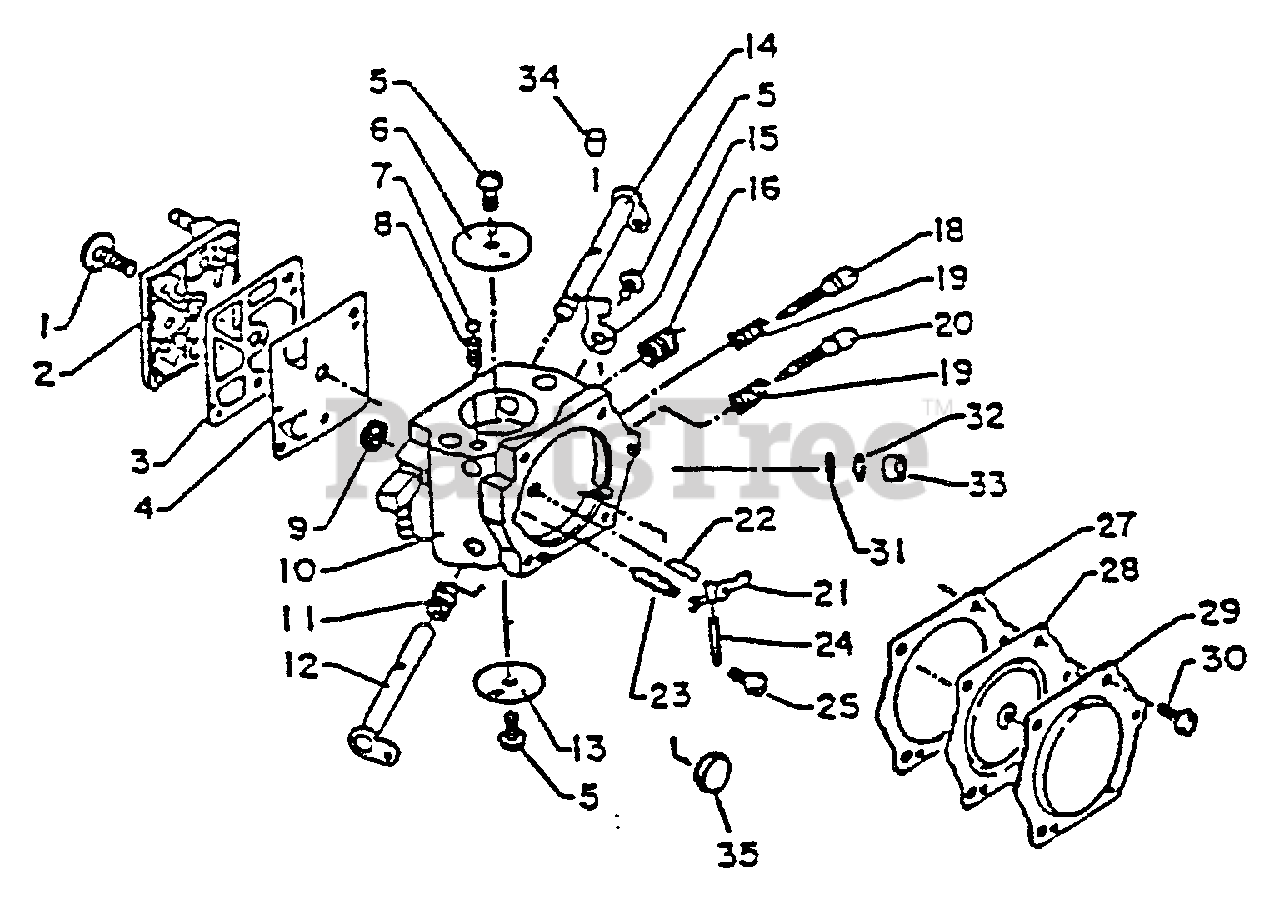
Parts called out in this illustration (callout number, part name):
1	SCREW, PUMP COVER
2	COVER, PUMP
3	GASKET, PUMP
4	DIAPHRAGM, PUMP
6	VALVE, CHOKE
7	BALL, CHOKE
9	STRAINER
10	BODY, CARBURETOR
11	SPRING, THROTTLE RETURN
12	SHAFT, THROTTLE
13	VALVE, THROTTLE
14	SHAFT, CHOKE
15	STOP, THROTTLE
16	SPRING, IDLE ADJUST
18	NEEDLE - LOW SPEED
19	SPRING, IDLE ADJUST
20	NEEDLE - HIGH SPEED
21	LEVER, METERING
22	SPRING, METER LEVER
23	VALVE, INLET NEEDLE
24	PIN, METERING LEVER
25	SCREW, METERING LEVER PIN
27	GASKET, METERING
28	DIAPHRAGM, METERING
29	COVER, METERING
30	SCREW
31	STRAINER
32	PIN, RETAINING
33	PLUG, WELCH
35	PLUG, WELCH
